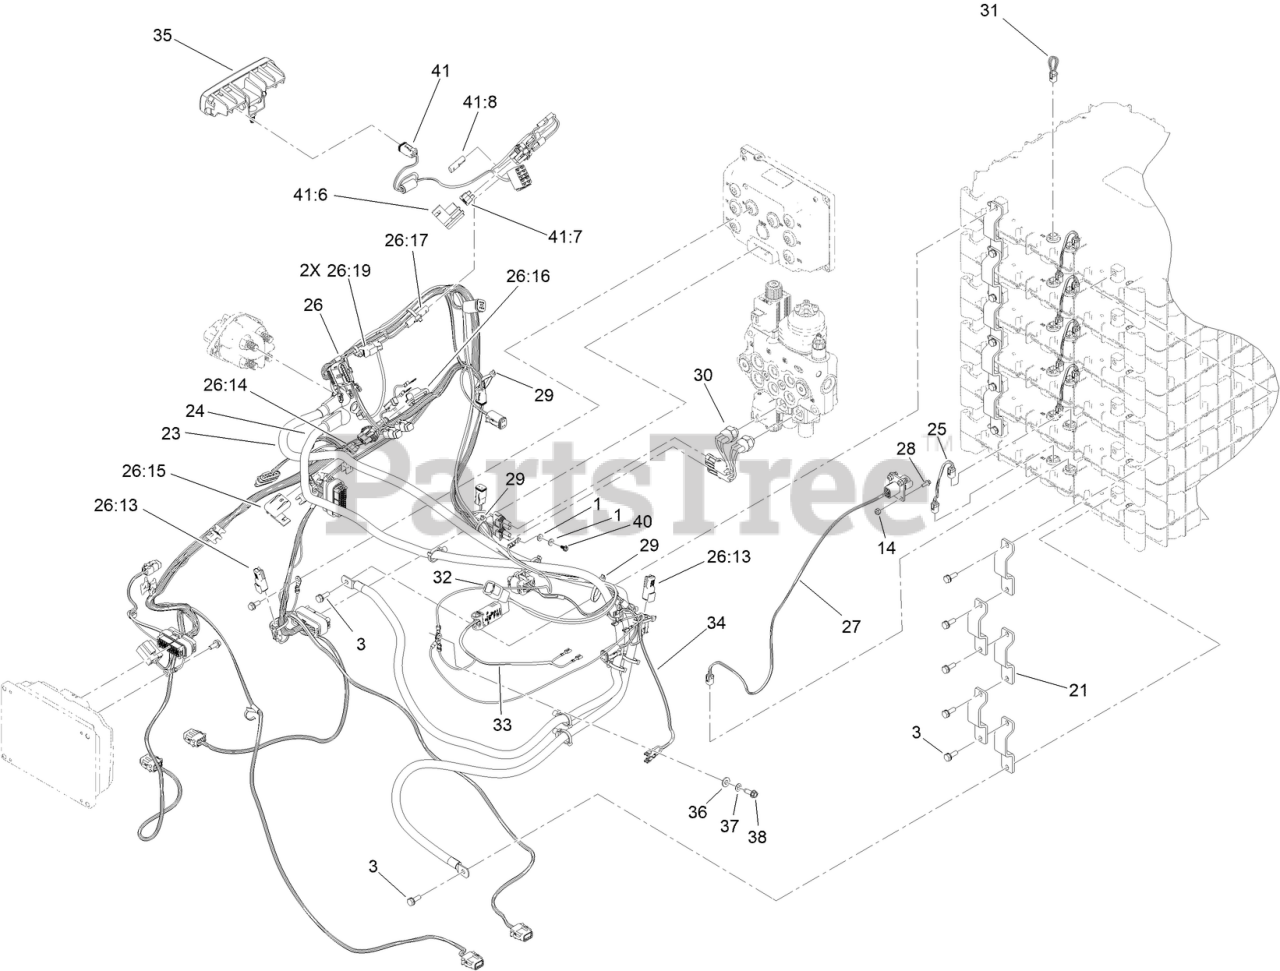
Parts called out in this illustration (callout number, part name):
1	WASHER-FLAT
3	SCREW-SEMS
14	NUT-LOCK
21	BAR-BUS, 400A
23	CABLE-BATTERY, RD ASM
24	CABLE-BATTERY, BK ASM
25	HARNESS-WIRE, DATA INTERFACE
26	HARNESS-WIRE, MAIN
26:13	RESISTOR-120 OHM
26:14	FUSE-BLADE, 10A
26:15	COVER-FUSE, SINGLE
26:16	CAP-PLUG, 3 WAY
26:17	CAP-PLUG
26:19	CAP-DUST, 2 WAY
27	HARNESS-WIRE, PACK COMM
28	SCREW-HHF, SERRATED
29	TIE-CABLE
30	SWITCH-BALL
31	HARNESS-WIRE, CAN TERMINATOR
32	HARNESS-WIRE, JUMPER
33	HARNESS-WIRE, AC CHARGER
34	HARNESS-WIRE, AC CHARGER
35	LIGHT-WORK, LED BAR
36	WASHER-FLAT
37	WASHER-SPRING
38	SCREW-HWHTF
40	SCREW-GROUND
41	HARNESS-WIRE, LIGHT KIT
41:6	COVER-FUSE, SINGLE
41:7	FUSE-BLADE, 3A
41:8	CAP-PLUG
